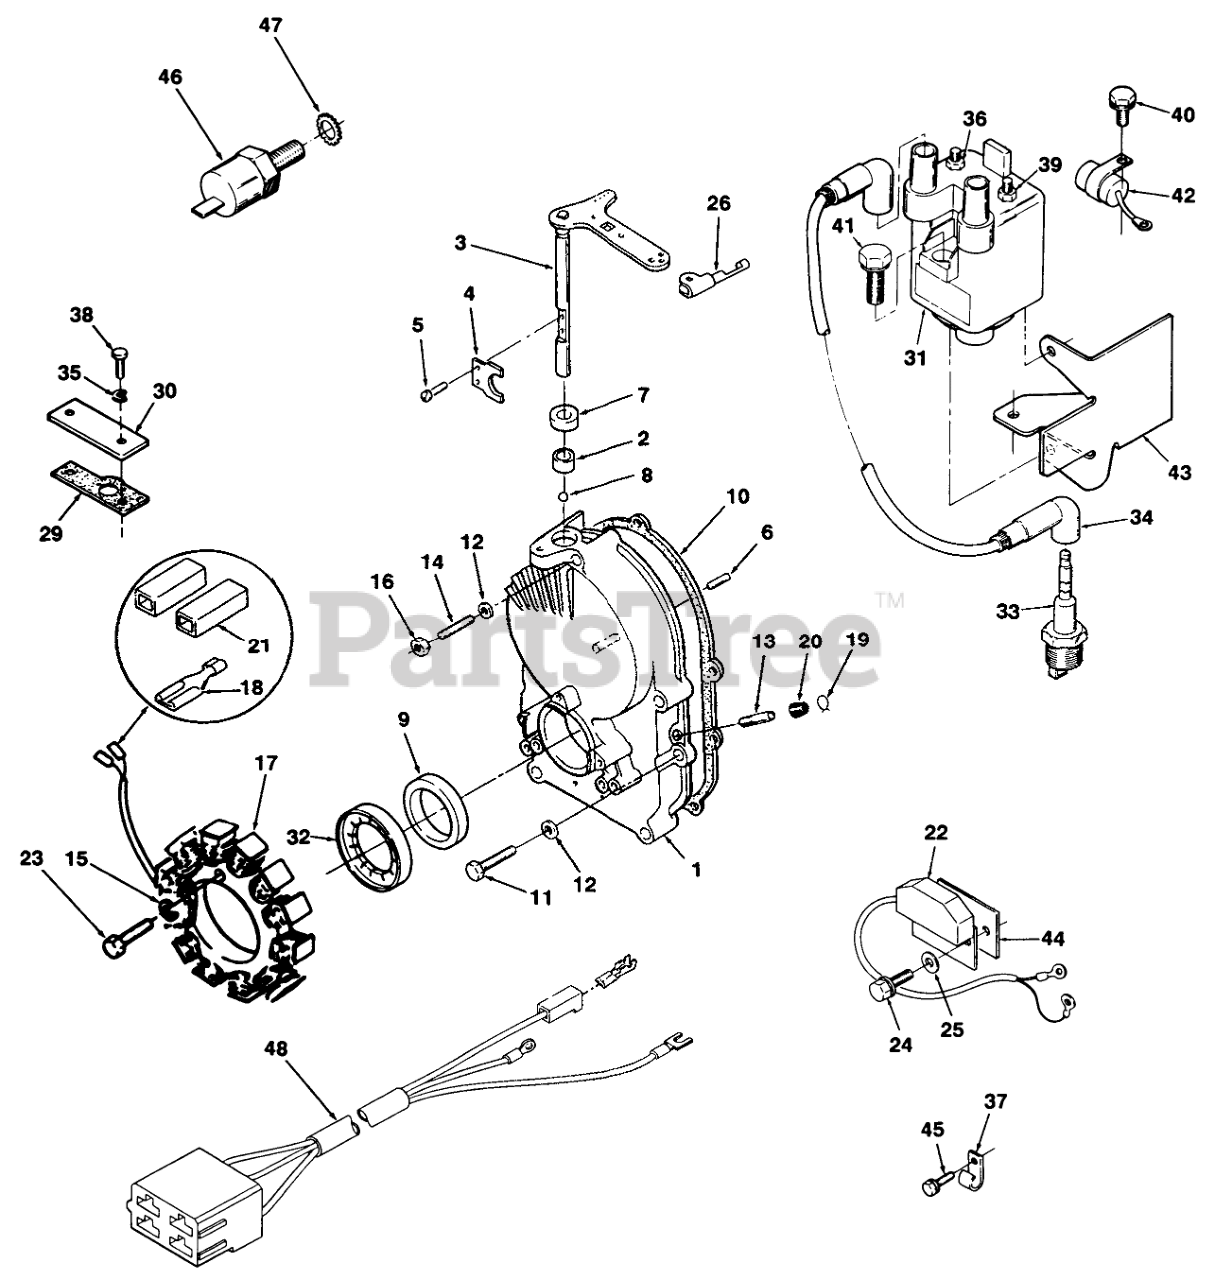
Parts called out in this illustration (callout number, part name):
1	Gearcase Kit (Includes items 2 thru 9)
2	BEARING
3	Governor Shaft & Arm Chromed
5	SCREW-PAN HD
6	PIN-DOWEL
10	Gasket
11	Bolt
12	WASHER
13	TUBE-PORT, VACUUM
14	STUD-GEAR COVER
15	Washer-Lock
16	NUT-GEAR COVER
17	Stator
18	TERMINAL
19	CLAMP
20	CAP-FUEL OUTLET
21	Terminal Connector Body Kit (Includes Terminals)
22	Control-Ignition
23	Screw-HH
24	Bolt
25	WASHER-LOCK
29	Gasket-Plate
30	PLATE-COVER
31	COIL-BATTERY IGNITION
32	ROTOR-IGNITION
33	SPARK PLUG
34	Wire-Plug
35	WASHER-FLAT
36	Nut
37	CLIP-WIRE
38	SCREW - CAP HEX HEAD
39	Nut
40	HEX HD CAPSCREW
41	Bolt
42	CONDENSER
43	BRACKET - COIL MTG
44	Insulator
45	Screw-Cap Hex Hd.
46	HIGH TEMPERATURE
47	WASHER-LOCK EXT TO
48	WIRING-HARNESS
